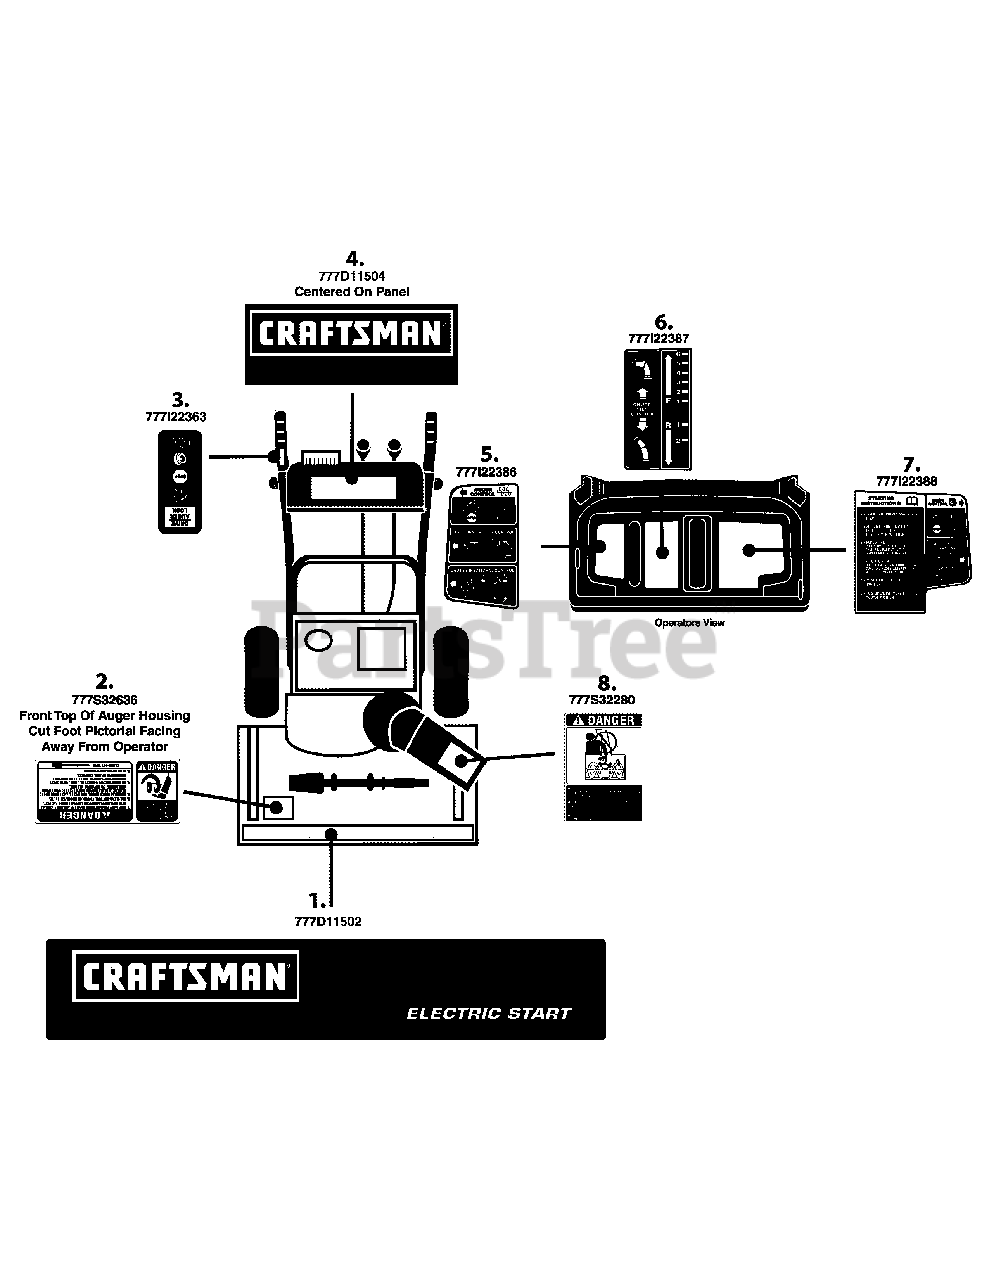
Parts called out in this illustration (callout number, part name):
1	LABEL-SNOW CRAFTSMAN PRO 33"
2	LABEL-SNOW HOUSING
4	LABEL-SNOW PANEL 6 STYLE CRAFTSMAN
5	LBL:SNO: 8 STYLE
6	LBL:SNO:8 STYLE
7	LBL:SNO: 8 STYLE R
8	LABEL-CHUTE
